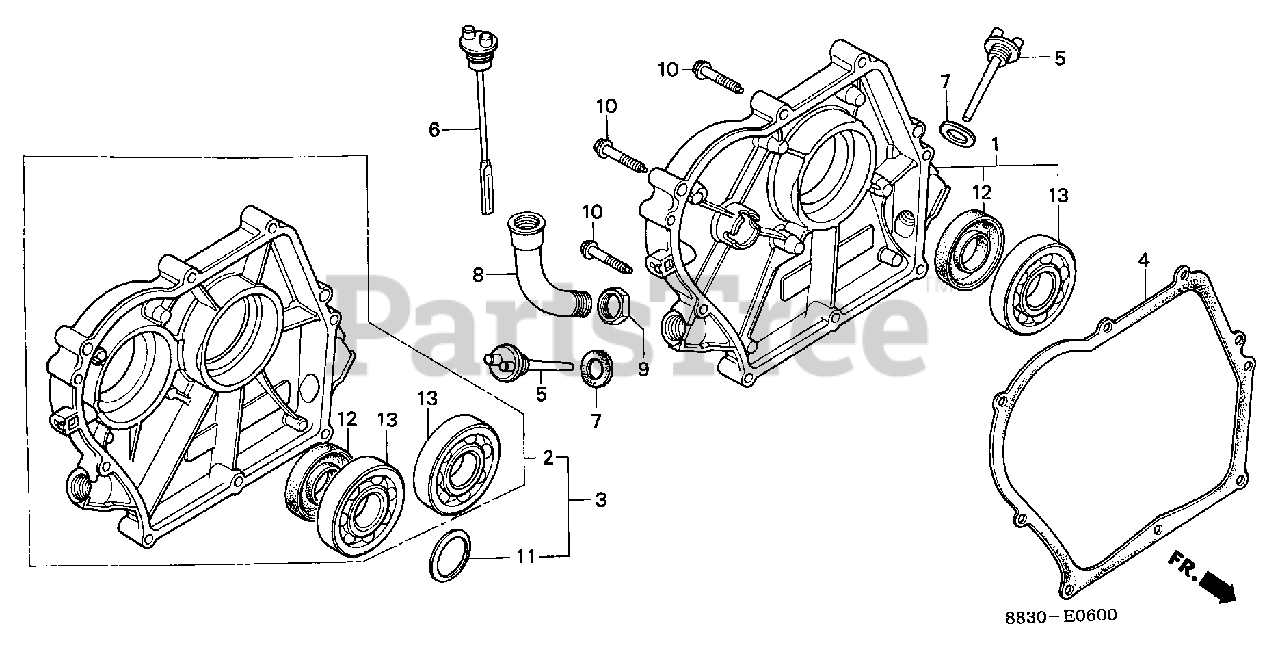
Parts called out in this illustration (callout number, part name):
1	COVER ASSY., CRANKCASE
4	GASKET, CASE COVER
5	CAP, OIL (YELLOW)
6	CAP, OIL (YELLOW)
9	NUT, OIL FILLER
10	BOLT, FLANGE (6X32)
12	OIL SEAL (25X41X6)
13	BEARING, RADIAL BALL (6205)
